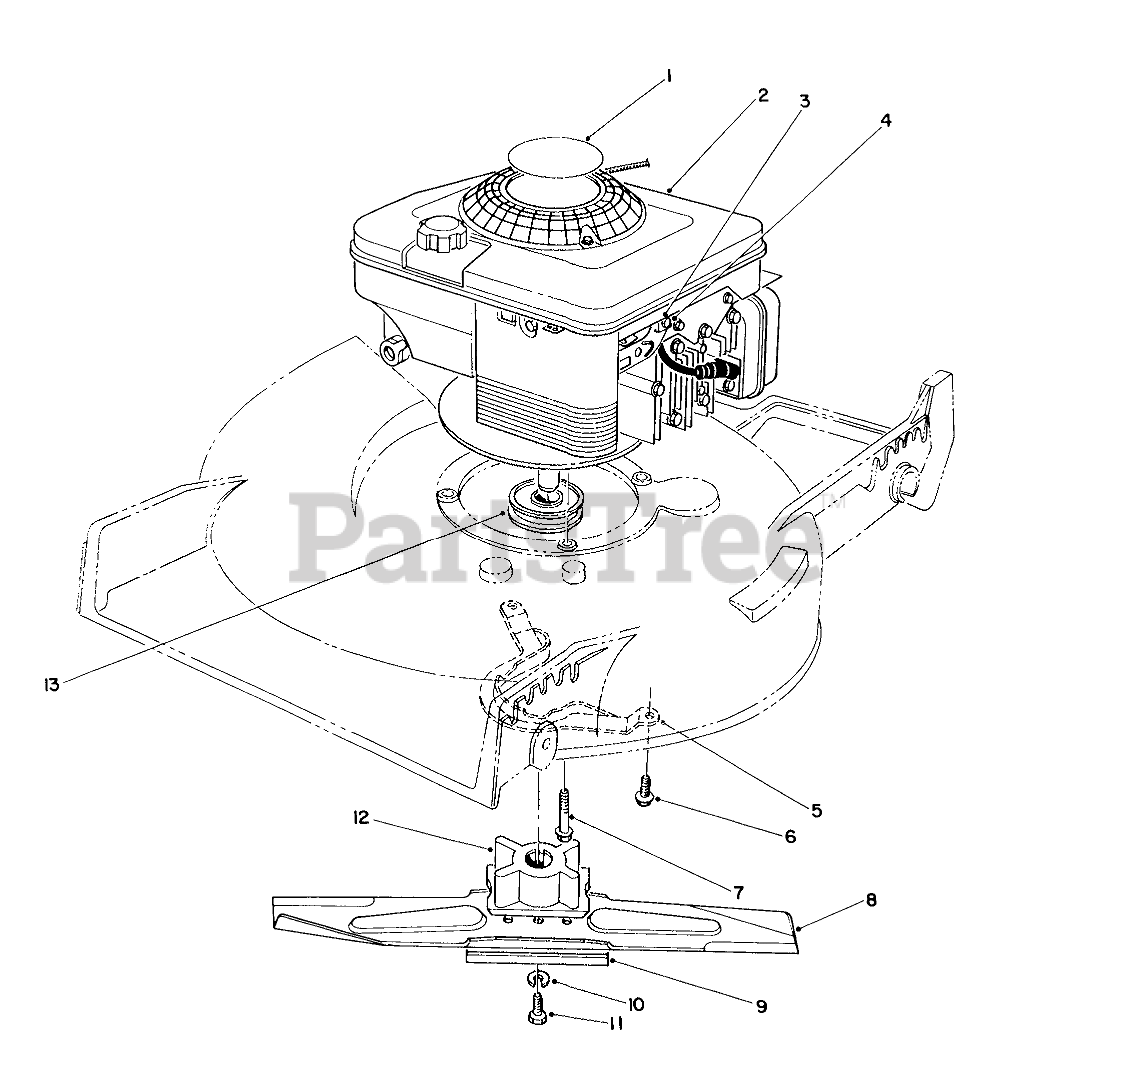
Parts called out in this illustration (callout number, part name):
1	DECAL - ENGINE
3	CLAMP-CASING
4	Screw
5	BELT GUIDE
6	SCREW-HWHTF
7	SCREW-HWH
8	Blade
9	Stiffener-Blade
10	WASHER-LOCK
11	SCREW-BLADE
12	BLADE RETAINER
13	PULLEY-DRIVE, ZONE START
